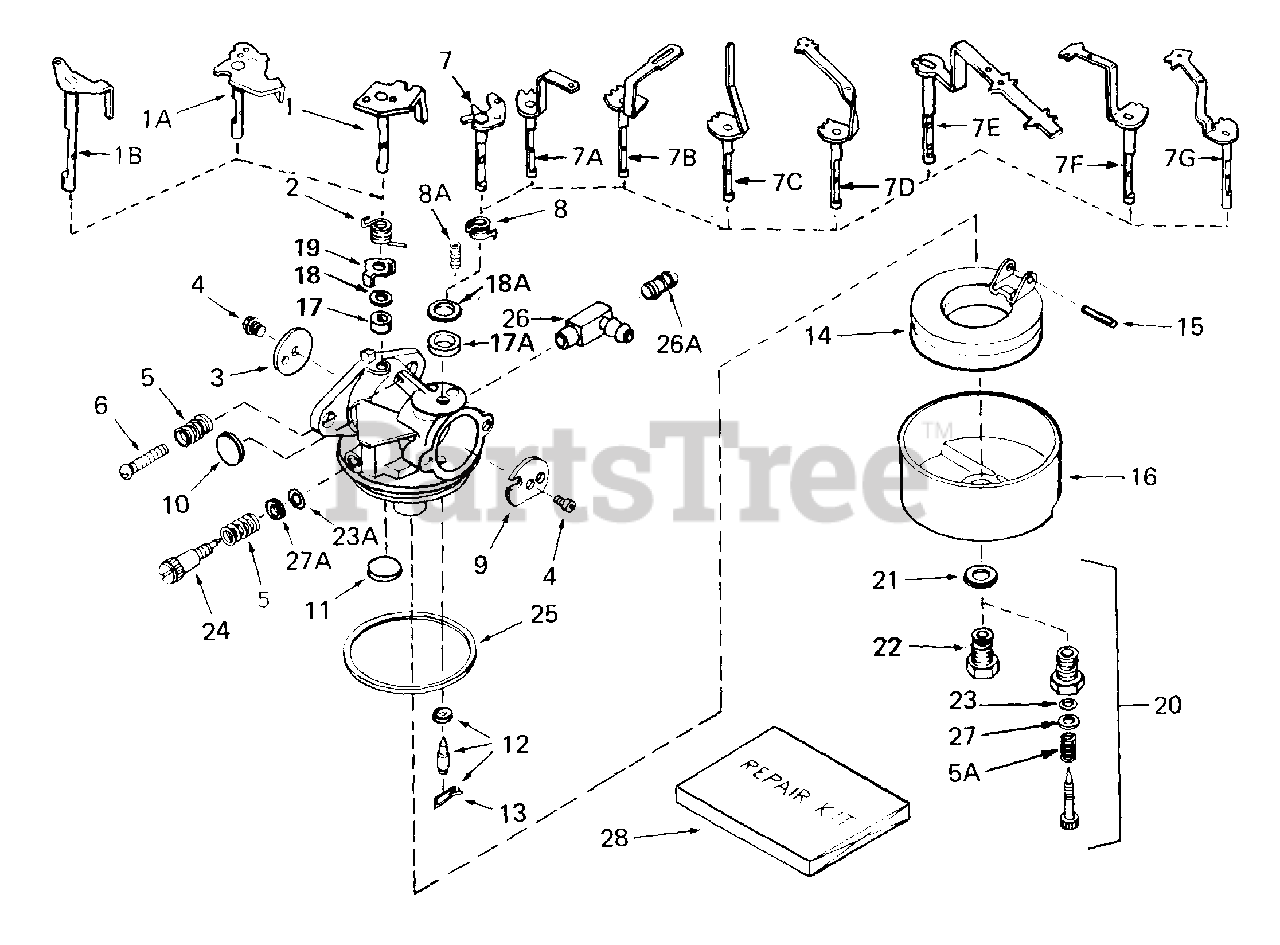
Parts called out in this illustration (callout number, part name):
1	"Shaft & Lever Assy., Throttle
2	Spring, Throttle return
3	Shutter, Throttle
4	Screw, Throttle & Choke shutter
5	Spring, Regulating screw . .
6	Screw, Idle regulating
7B	Shaft & Lever Assy., Choke
8A	Spring, Choke positioning
9	Shutter, Choke
10	Plug, Welch
11	Plug, Welch
12	Inlet Needle, Seat & Clip Assy.
13	Clip, Inlet needle
14	Float, Carburetor
15	Shaft, Float
16	Bowl, Float
21	Gasket, Bowl-to-body
22	Nut, Float bowl:
24	Screw, Idle adjustment
25	Gasket, Bowl-to-body
26A	Fitting, Fuel inlet
